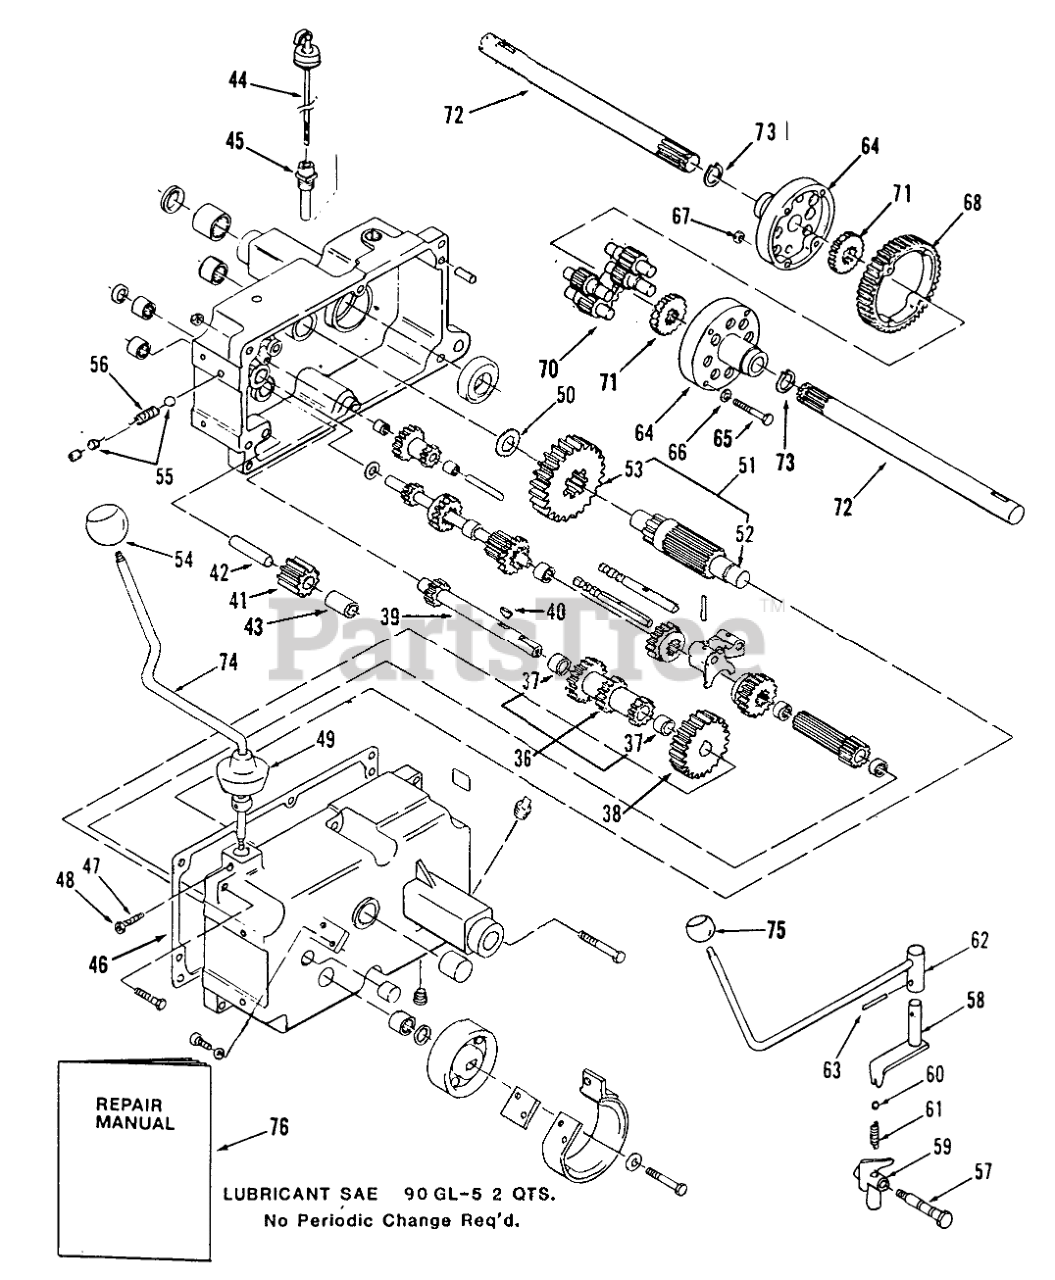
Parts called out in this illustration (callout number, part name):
36	GEAR-CLUSTER
37	BUSHING-BRONZE
38	GEAR-CLUSTER SHAFT
39	Cluster Shaft
40	KEY-WOODRUFF
41	GEAR/BUSHING ASM-REVERSE IDLER
42	PIN-DIFFERENTIAL
43	BUSHING
44	ASSY-DIPSTICK
45	NIPPLE-TRANS FILL
46	GASKET-TRANSMISSION
47	SETSCREW
48	Nut
49	COVER-DUST
50	WASHER-THRUST
51	GEAR ASM
52	PINION SHAFT
55	BALL-DETENT
56	SPRING-SHIFT STOP
57	BOLT-DETENT
58	SHIFT ASM
59	SHIFT FORK ASM
60	BALL-DETENT
61	SPRING-SHIFT STOP
62	SHIFT ROD ASM
63	PIN-SPIROL
64	END CAP-DIFFERENTIAL
65	Bolt 3/8-16 x 3 1/4
66	WASHER
68	DIFFERENTIAL BULL GR
70	GEAR-PINION, 11T
71	AXLE GEAR
72	AXLE-REAR
73	Snap Ring
74	ASM-Rod
75	Knob
76	MANUAL
